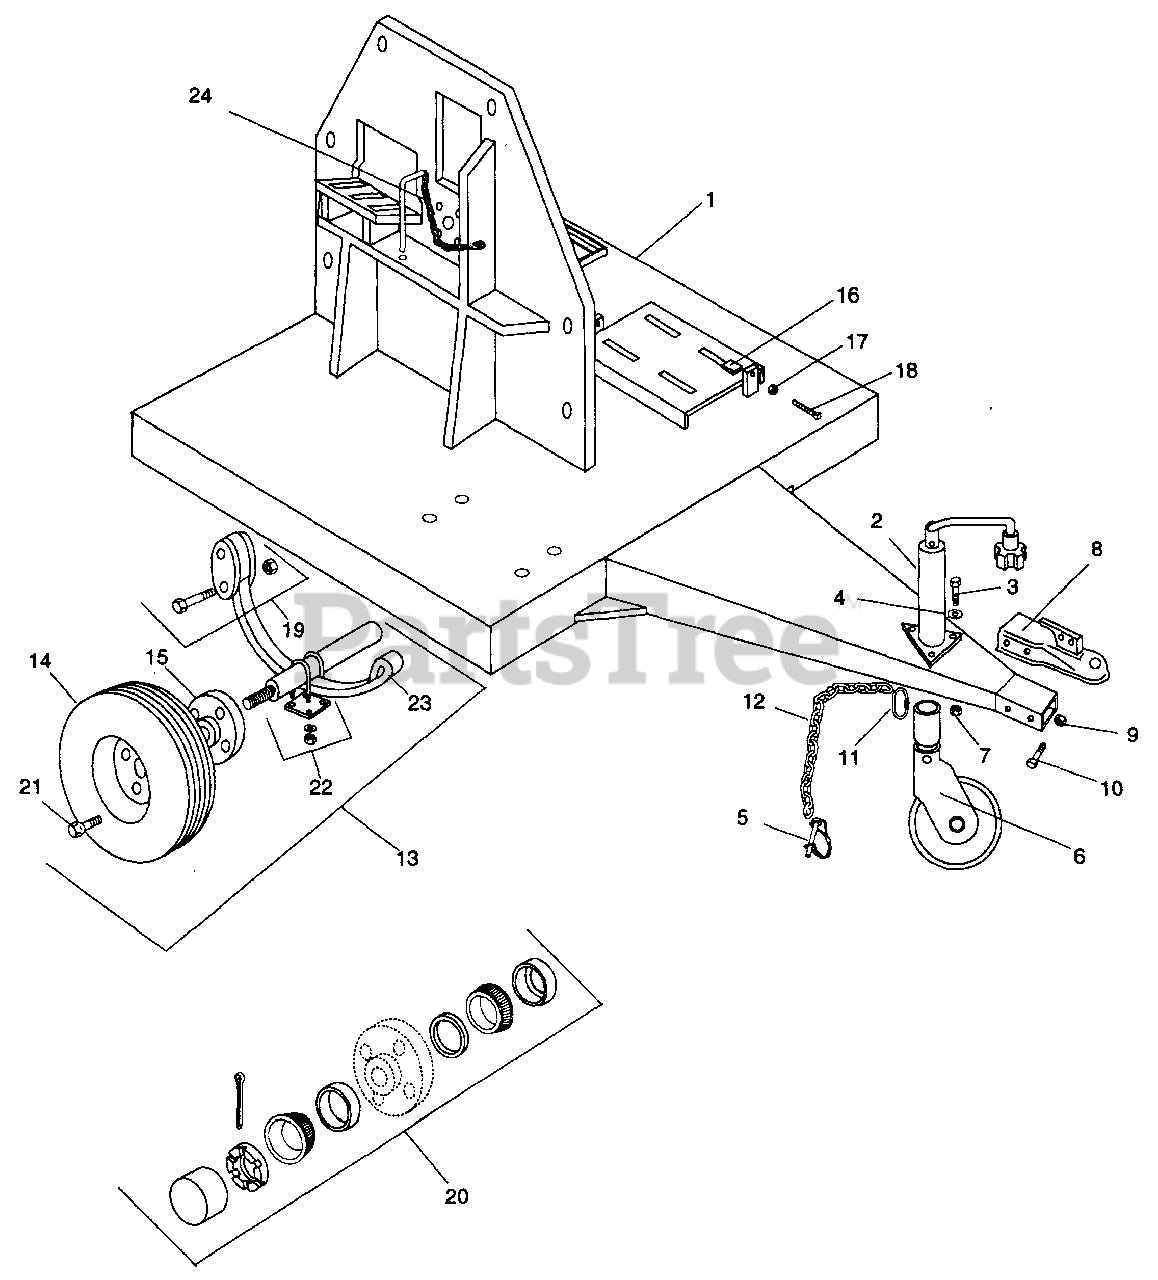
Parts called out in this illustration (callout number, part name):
1	TRAILER BED
2	JACK ASSEMBLY
3	BLT HEX .44-14X1.25 PL GR 5
4	WSHR-FL-STL .438X1.0X.083 PL
5	QUICK LATCH PIN JACK WHEEL
6	SWIVEL WHEEL
7	NUT-LK-CROWN .437-14 PL
8	2" COUPLER BALL TYPE
9	NUT-LK-CTR .500-13 PL
10	BLT-HEX .50-13X4.00 GR 8 PL
11	QUICK LINK 5/16 SAFETY TYPE
12	SAFETY CHAIN INCLUDES "S" HOOK
13	TRAILER AXLE COMPLETE-(LESS TIRE)
14	TIRE & WHEEL ASSEMBLY
15	AXLE HUB, COMPLETE
16	ENGINE ADJUSTMENT BLOCK
17	NUT-HEX .375-16
18	SCR-SET .38-16X3.50 SQH PL
19	HARDWARE KIT LUG BOLT DEXTER
20	BEARING KIT DEXTER AXLE 2000#
21	WHEEL BOLT KIT DEXTER AXLE
22	U-BOLT KIT DEXTER AXLE 2000#
23	AXLE SPRING
24	FLYWHEEL LOCK PIN
